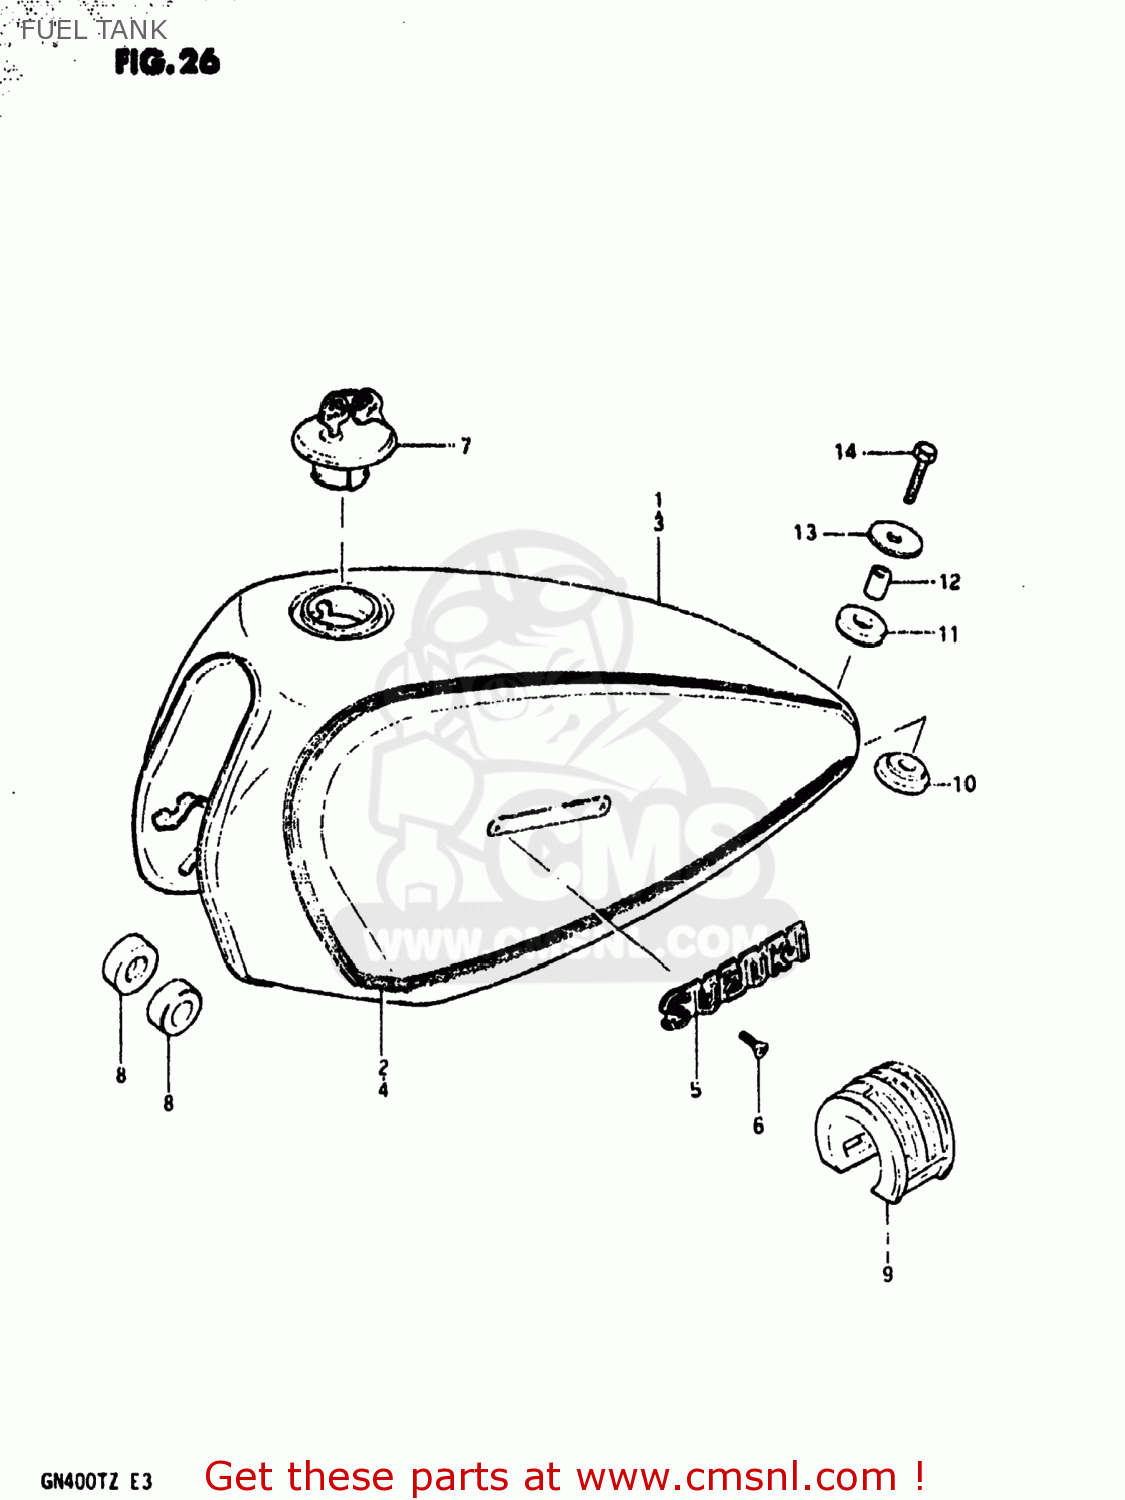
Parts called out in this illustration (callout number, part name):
1	TANK ASSEMBLY,FUEL
2	TAPE SET,FUEL TANK
3	TANK ASSEMBLY,FUEL
4	TAPE SET,FUEL TANK
5	EMBLEM,FUEL TANK
6	SCREW 3X6
7	CAP SET,FUEL TANK
8	CUSHION
9	CUSHION,FUEL TANK
10	CUSHION
11	CUSHION
12	SPACER
13	WASHER (8.5X29X1.6)
14	BOLT (8X30)
